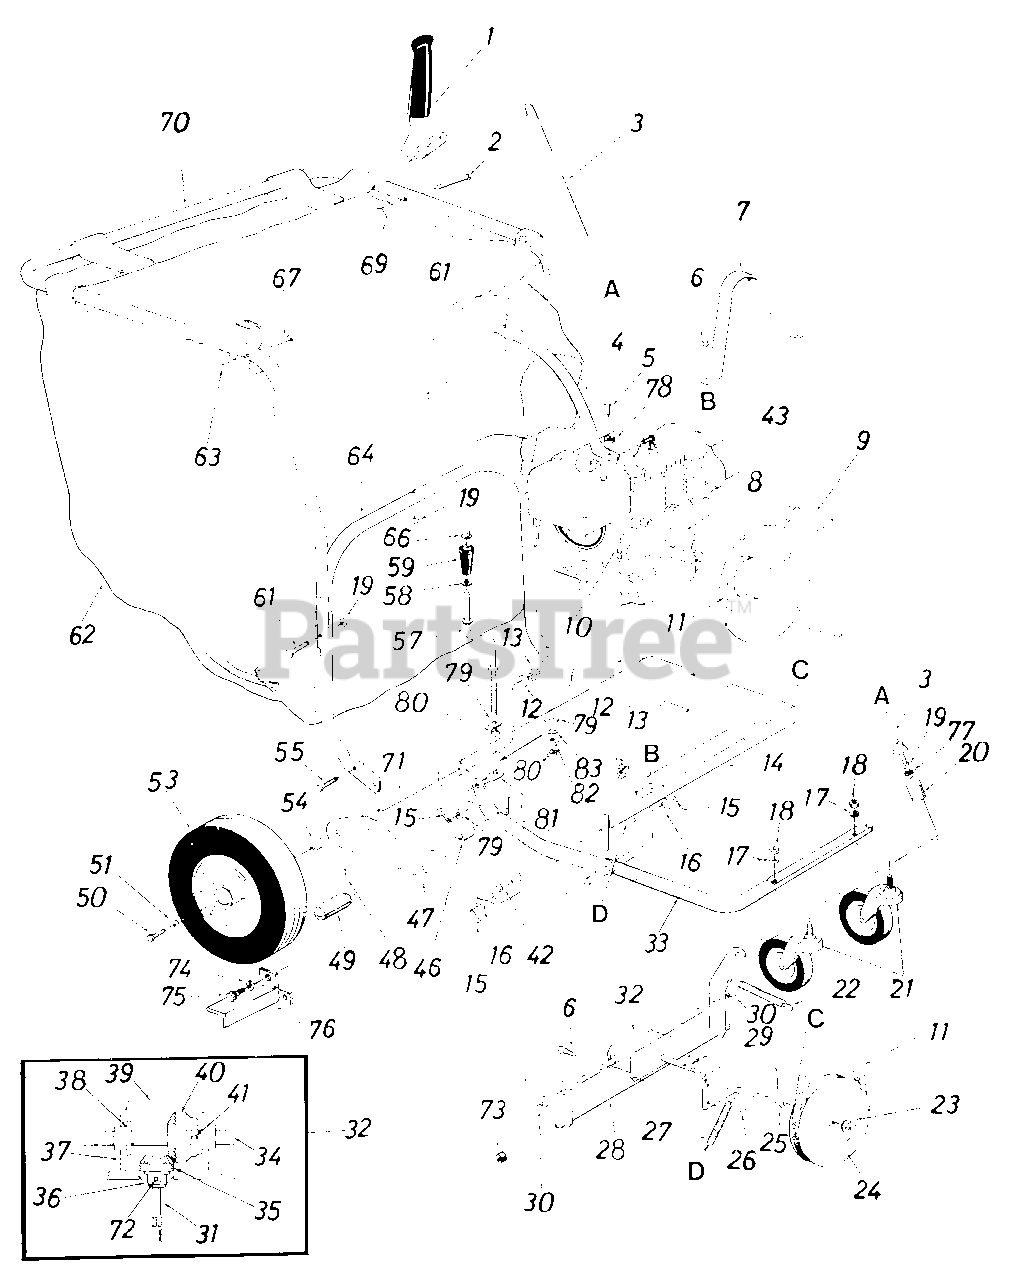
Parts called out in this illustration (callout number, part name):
1	Clutch Grip Ass'y.
2	Clevis Pin .375" Dia. x 1.88"
3	Clutch Rod 32" Lg.
4	Handle Brace (Painted)
5	Part of Engine
6	Hex L-Wash. Hd. AB Tap Scr. 1/4" x .62" Lg.
9	Air Vane Plate Ass'y.
11	"V"-Belt 1/2" x 26" Lg.
12	L.-Wash. 5/16" I.D.
13	Hex Nut 5/16-18 Thd.*
16	Fl.-Wash. .63" I.D. x 1.25" O.D.
17	L.-Wash. 1/2" I.D.*
18	Hex Nut 1/2-13 Thd.*
19	Hex Cent. L.-Nut 1/4-20 Thd.
20	Extension Spring .78" O.D. x .75" Lg.
21	Swivel Caster Wheel 5" Dia. x 1.25"
22	Extension Spring .38" O.D. x 7.50" Lg.
23	Snap "E"-Ring.50" Dia. Shaft
24	"V" -Pulley 5/8" x 6.50" O.D.
25	Flange Bearing .502" I.D.
28	Clutch Bracket Ass'y.
29	#2 Woodruff Key 3/32" Dia. x .81 " Lg.
30	Hex Flange Bearing Bronze .625 " I . D .
31	Pinion Shaft .50" Dia. x 5.0"
32	Gear Box Ass'y. Comp.
35	Bevel Gear .50" I.D. x 14 Teeth
36	Flange Bearing .503" I.D.
37	Gear Box
38	Flange Bearing .630" I.D.
39	Gear Box Cover
40	Bevel Gear .62" I.D. x 28 Teeth
41	Spring Pin Spiral 3/16" Dia. x 1.25" Lg.
42	Hex Wash. Hd. "AB" Tap Scr. 5/16" x .75" Lg.
43	Engine
46	Spacer .63 I.D. x .88" O.D. x.56" Lg.
49	Drive Pinion
50	Hex Locking BoIt 5/16-24 x .62 " Lg.
51	Fl.-Wash. .34" I.D. x .87" O.D.
53	Wheel Ass'y. - Comp. 12" x 3" (Incl. Ball Bearings)
54	Spacer .63" I.D. x 1.00" O.D. x.94" Lg.
55	Hex Bolt 5/16-18 x .75" Lg.*
57	Height Adjustment Crank
58	Fl.-Wash. 138" I.D. x .62" O.D.
59	Crank Knob
61	Hex BoIt 1/4-20 x 1.75" Lg.
62	Vacuum Bag- Felt
63	Push Speed Nut .25" Dia. Stud
66	Push Nut 3/8" Dia.
67	Stud Pin .250" Dia. x 1.75"
69	Internal Cotter Pin 3/8" Dia.
70	Upper Handle (Painted)
71	Rear Axle .624" Dia. x 24.37"
72	Spring Roll Pin 5/32" Dia. x 1.12
73	Spacer .82" I.D. x 1.00" O.D. x .305 Lg.
74	L.-Wash. .265" I.D.
75	Hex Self Tap Scr. 1/4" x 3/8" Lg.
78	Belleville Washer
79	Fl.-Wash. .35" I.D. x .87" O.D.
80	Spacer .38" I.D. x .50" O.D. x .180" Lg.
81	Ferrule 3/8-8 x .38" Dia.
82	Hex Nut 3/8-8 Thd.
83	L.-Wash. 3/8 " 1. D. *
